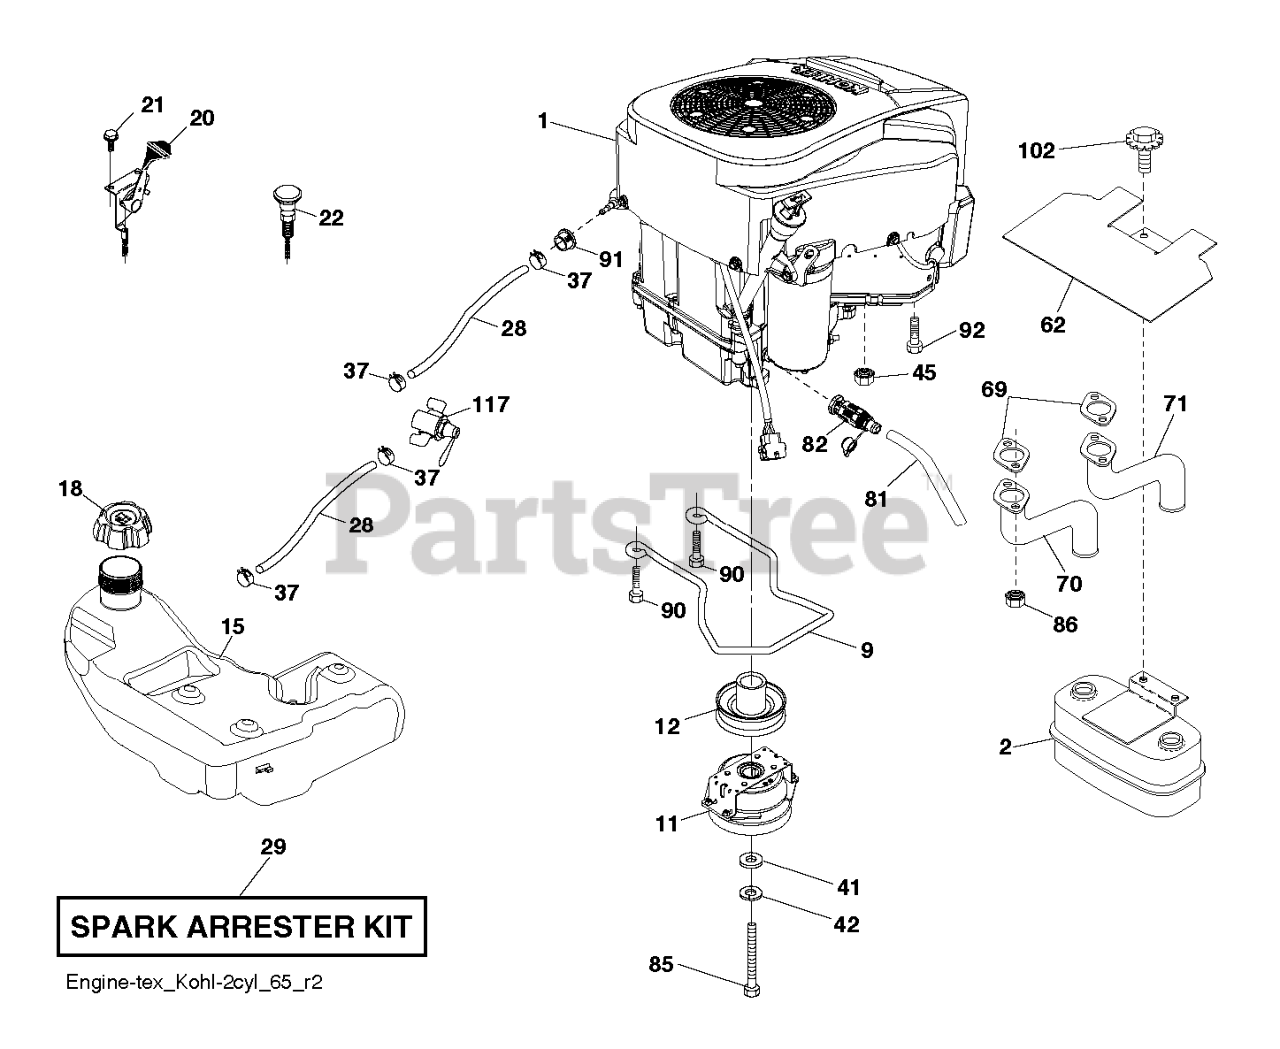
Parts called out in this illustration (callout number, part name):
2	MUFFLER.ASM.TWIN.MNTG.BRACKET
11	CLUTCH.OGURA.5.0PD.GT1.5A-EH01
12	PULLEY ENGINE
15	Tanks
18	CAP ASSY FUEL 3" GRAY
18	FUEL CAP
20	THROTTLE CONTROL
22	CONTROL.CHOKE.ERGO.PUSH-IN.BLA
28	LINE.FUEL.64"REAR.EMIS
29	KIT.SPARK ARRESTOR 794945 B&S
37	HOSE CLAMP
62	SHIELD.HEAT.MUFFLER
69	GASKET.EXHAUST.KOHL.CV18-CV26
70	PIPE.EXHAUST.LH.CV18/20
71	PIPE.EXHAUST.RH.CV18/20
81	TUBE, DRAIN OIL ASM.
82	VALUE.OIL.DRAIN
85	BOLT.HEX.7/16-20X3.GR5.YELLOW
86	NUT.HEX.FLANGE.TOPLOCK
90	SCREW 3/8-16X1
91	BUSHING.1.375OD
92	SCREW 3/8-16X1
102	SCREW
117	VALVE FUEL RESERVE
